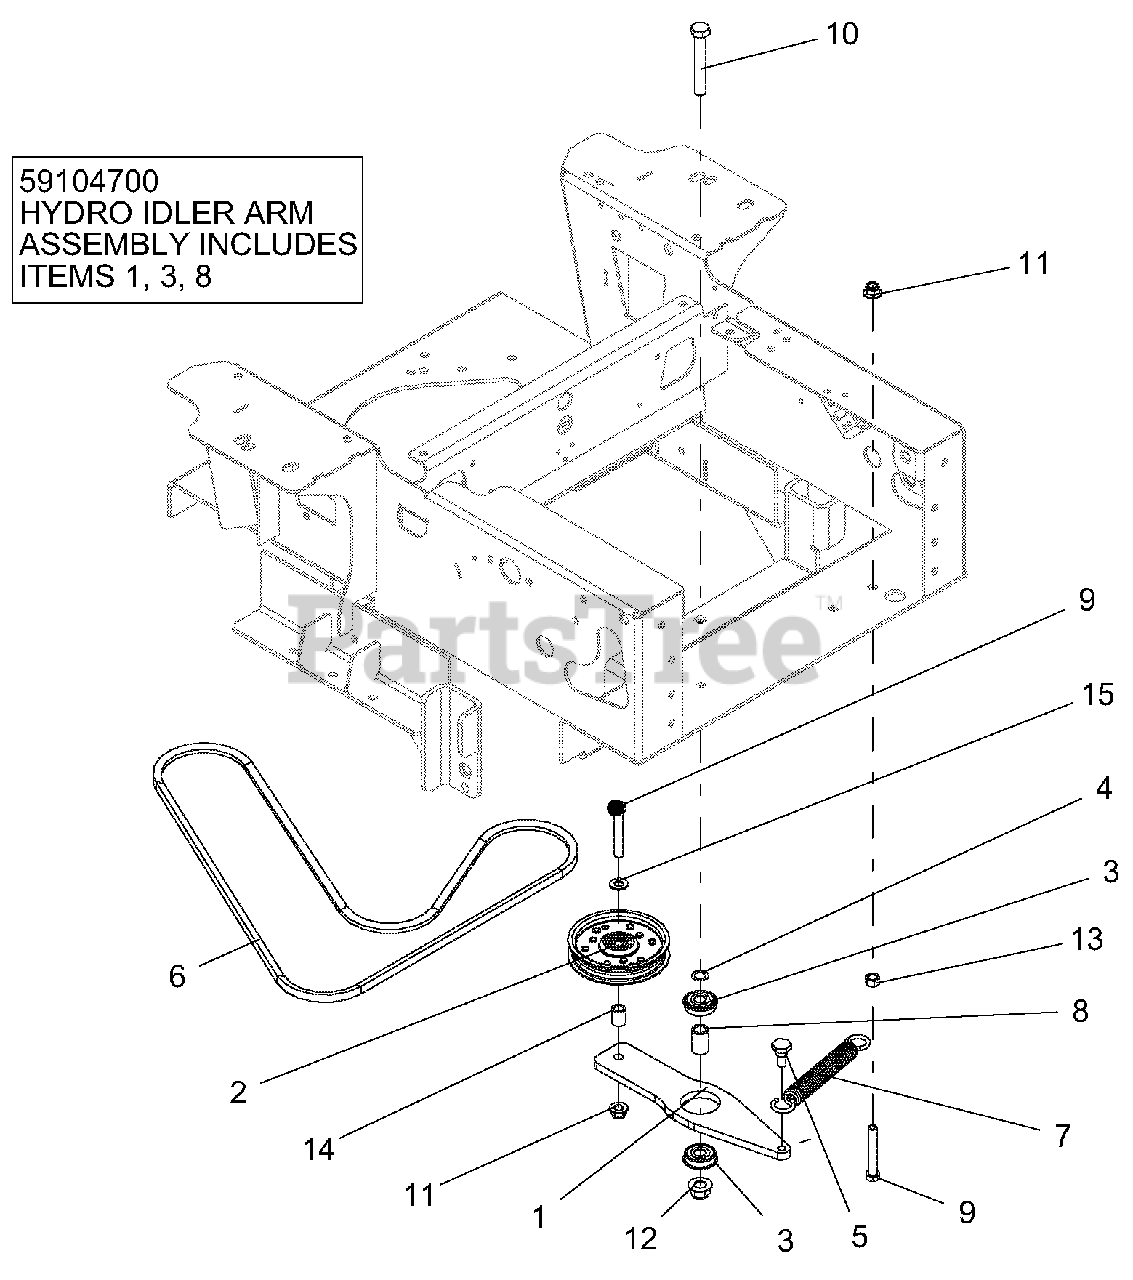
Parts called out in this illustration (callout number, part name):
1	WLDMT, HYDRO DRIVE IDLER ARM-BLACK
2	ASM, IDLER 4"
3	BRG, BALL .501 X 1.38 X .438 SEALED
4	WASHER-FLAT-STL, .500 X .750 X .020
5	BLT, SHLDR EP .38-16X.30 HEX YZ
6	BELT, V-A-COGGED
7	SPRG, EXTENSION
8	SPACER, .510 X .750 X 1.148
9	BLT-HEX .38-16X2.50 GR5 YWZC
10	BLT-HEX .50-13X3.25 GR5 YWZC
11	NUT-LK-NYL-FLG .38-16 YWZC
12	NUT-LK-NYL-FLG .50-13 YWZC
13	NUT-HEX .38-16 YWZC
14	BSHG-SLV .407X.625X.750
15	WSHR-FL-STL.406X.812X.065 YWZ
